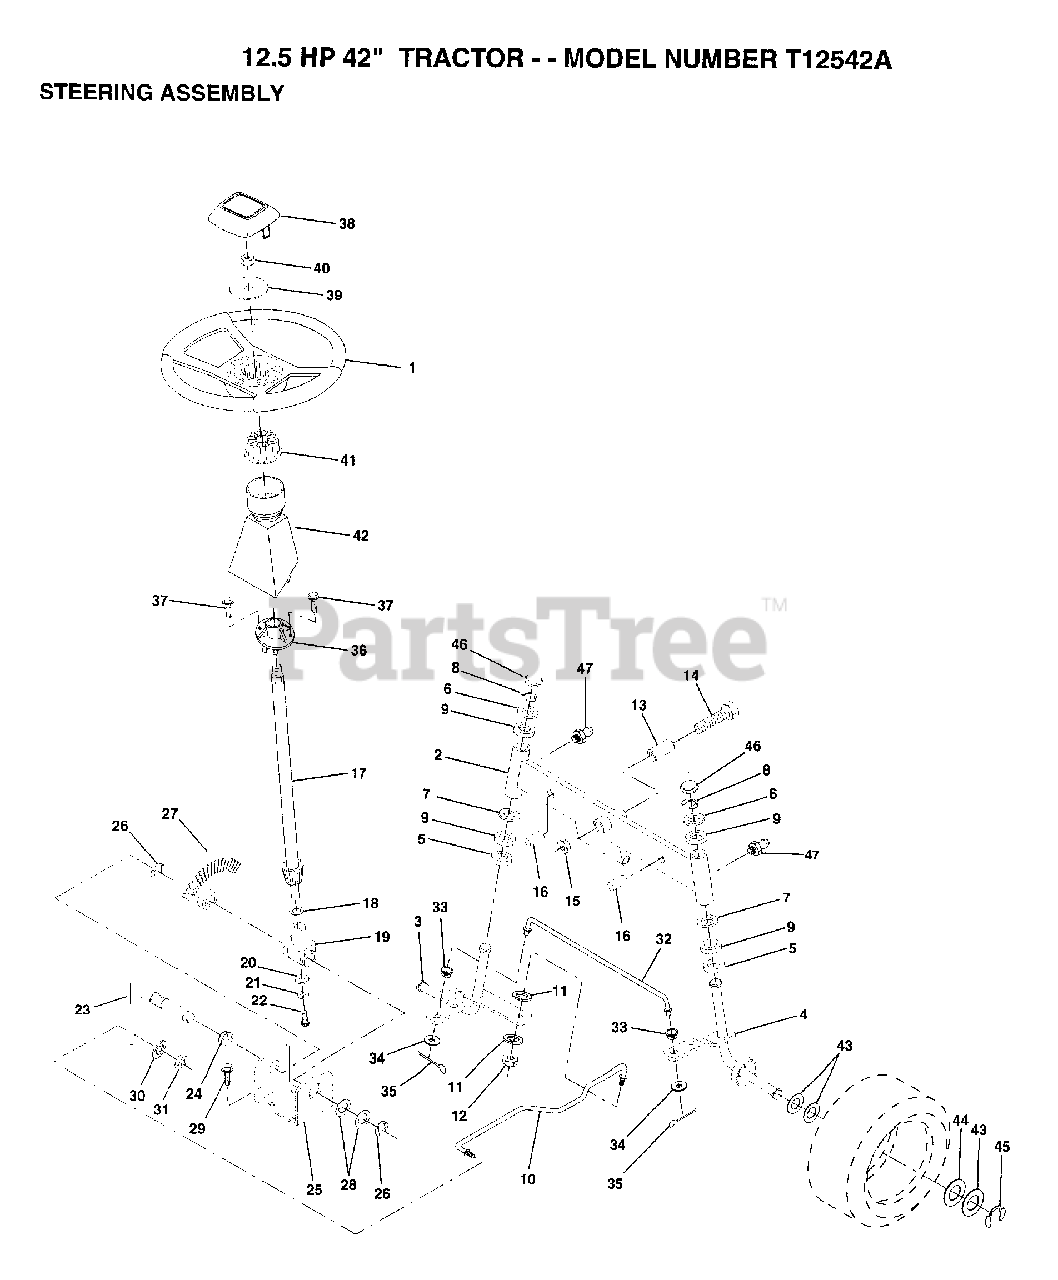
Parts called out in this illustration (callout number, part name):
3	SPINDLE LH
4	SPINDLE RH
5	WASHER .T
6	WASHER
7	WASHER
8	RING
9	COL. SRTG. BEAR.
11	LOCKWASHER
13	BEARING
14	BOLT HEX 5/8-11
15	"NUT-LOC,FLANGE LT"
16	AXLE PIN
17	SHAFT ASM
18	THRUST WASHER
19	SUPPORT.SHAFT
21	LOCKWASHER
22	"SCREW,SPECIAL"
24	NYLINER T
25	"BRKT,STEERING"
26	RING
27	GEAR SECTOR
28	WASHER .T
29	SCREW
30	LOCKWASHER
32	TIE ROD
33	BUSHING.DRAGLINK
34	WASHER
35	COTTER PIN
38	ST WHL INSERT CAP
39	WASHER T
40	GRIPCO NUT
41	ADAPTER-WHEEL LT
42	"TUBE, STR SHAFT"
43	WASHER
44	WASHER
45	RING
46	CAP
47	ZERK M
